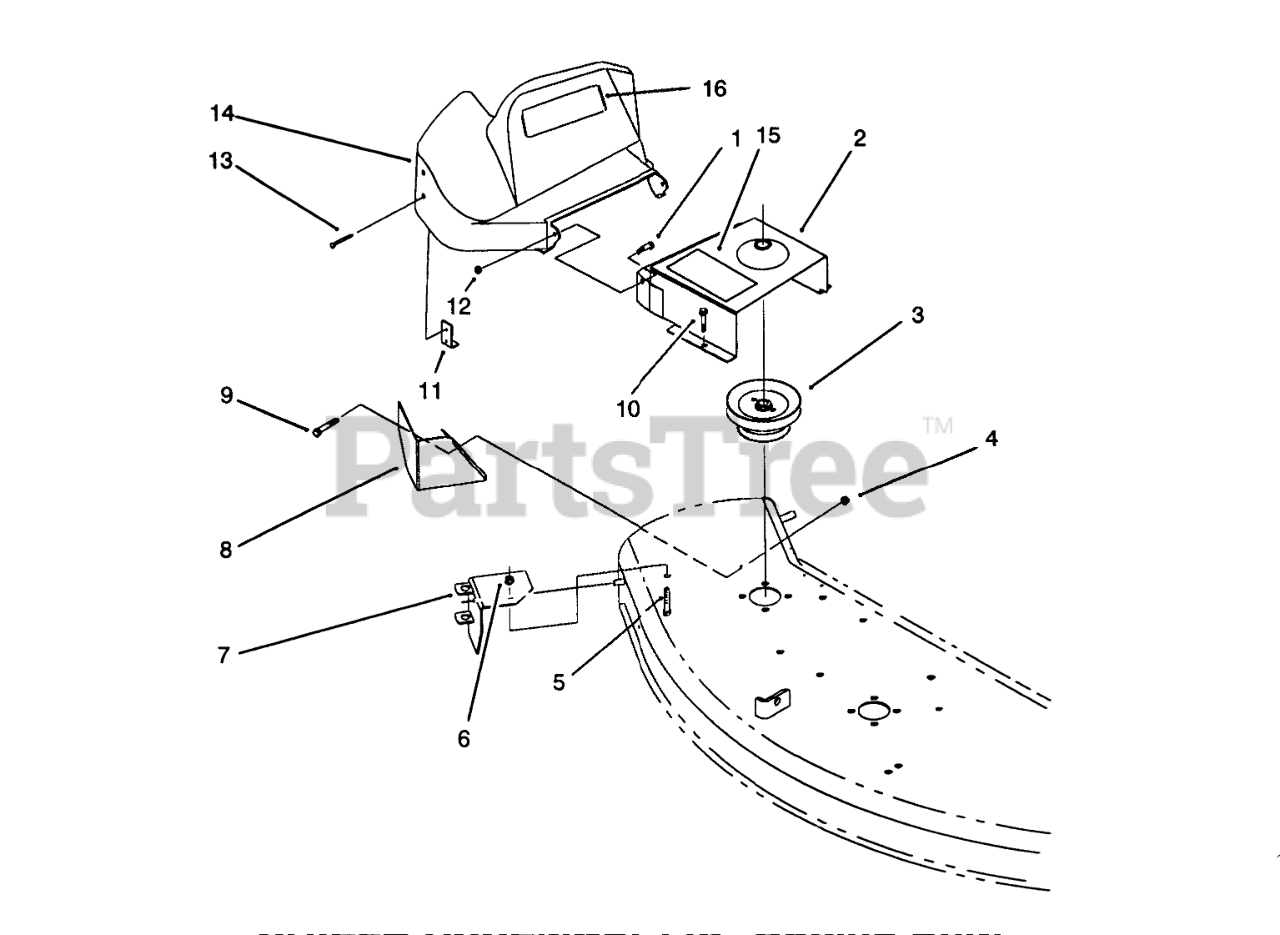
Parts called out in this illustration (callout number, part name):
1	SCREW-HH
2	48" Inner Shield Assembly (Incl. Ref. #15)
3	PULLEY
4	NUT-LOCK, NI
5	SCREW-HH
6	NUT-HF
7	PIVOT SUPPORT ASM
8	48" DEFLECTOR B
9	SCREW-CARR
10	Bolt
11	BRACKET-SUPPORT, SHIELD
12	NUT-LOCK, NI
13	RIVET-POP
14	Belt Shield Assembly (Incl. Ref. #16)
15	DECAL-DANGER, THROWN OBJECT
16	DECAL - DANGER
